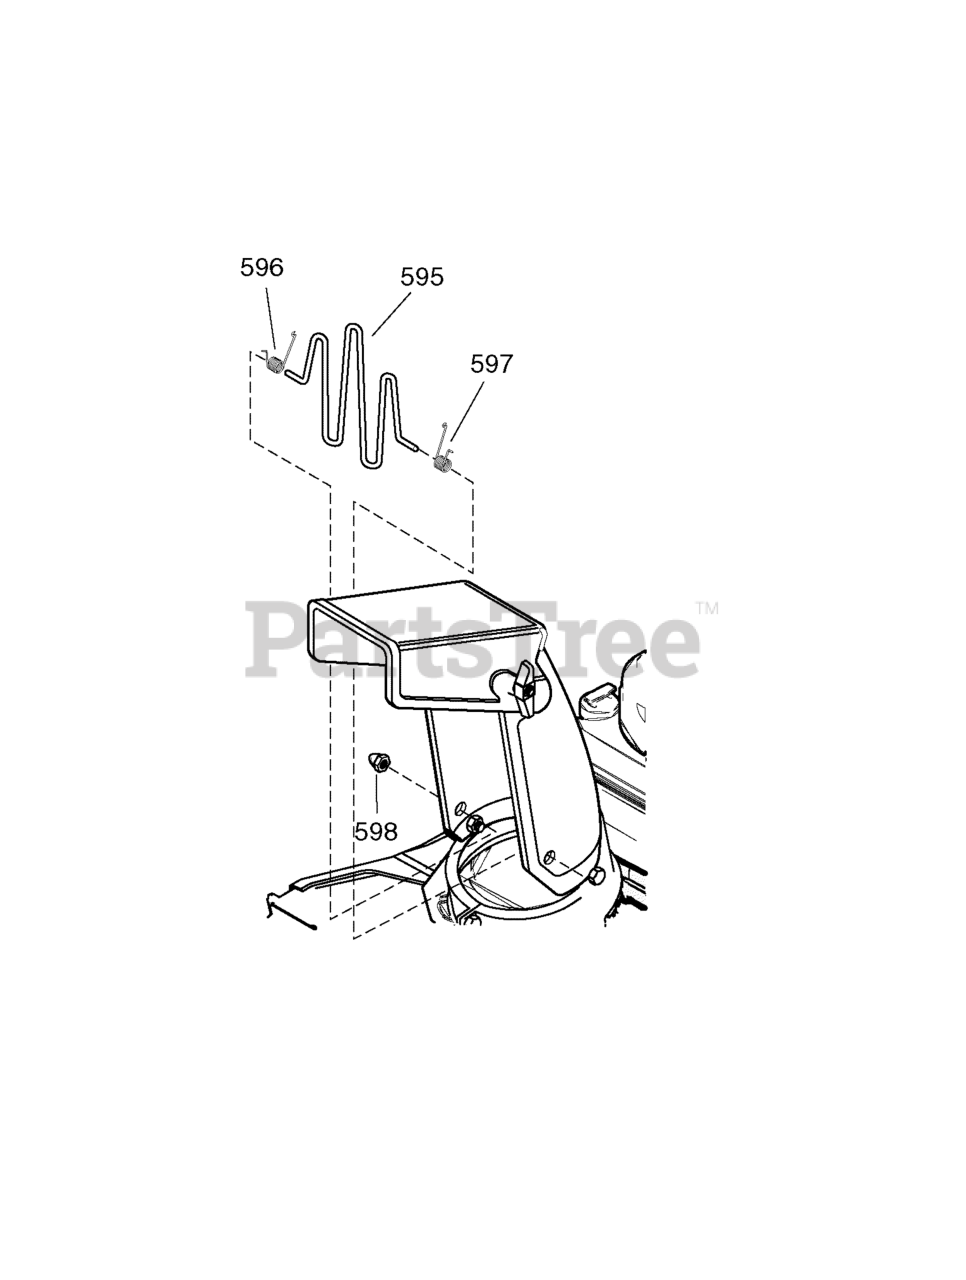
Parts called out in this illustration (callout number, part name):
595	GUARD, WIRE CHUTE
596	SPRING, TORSION
597	SPRING, TORSION
598	NUT, ACORN
